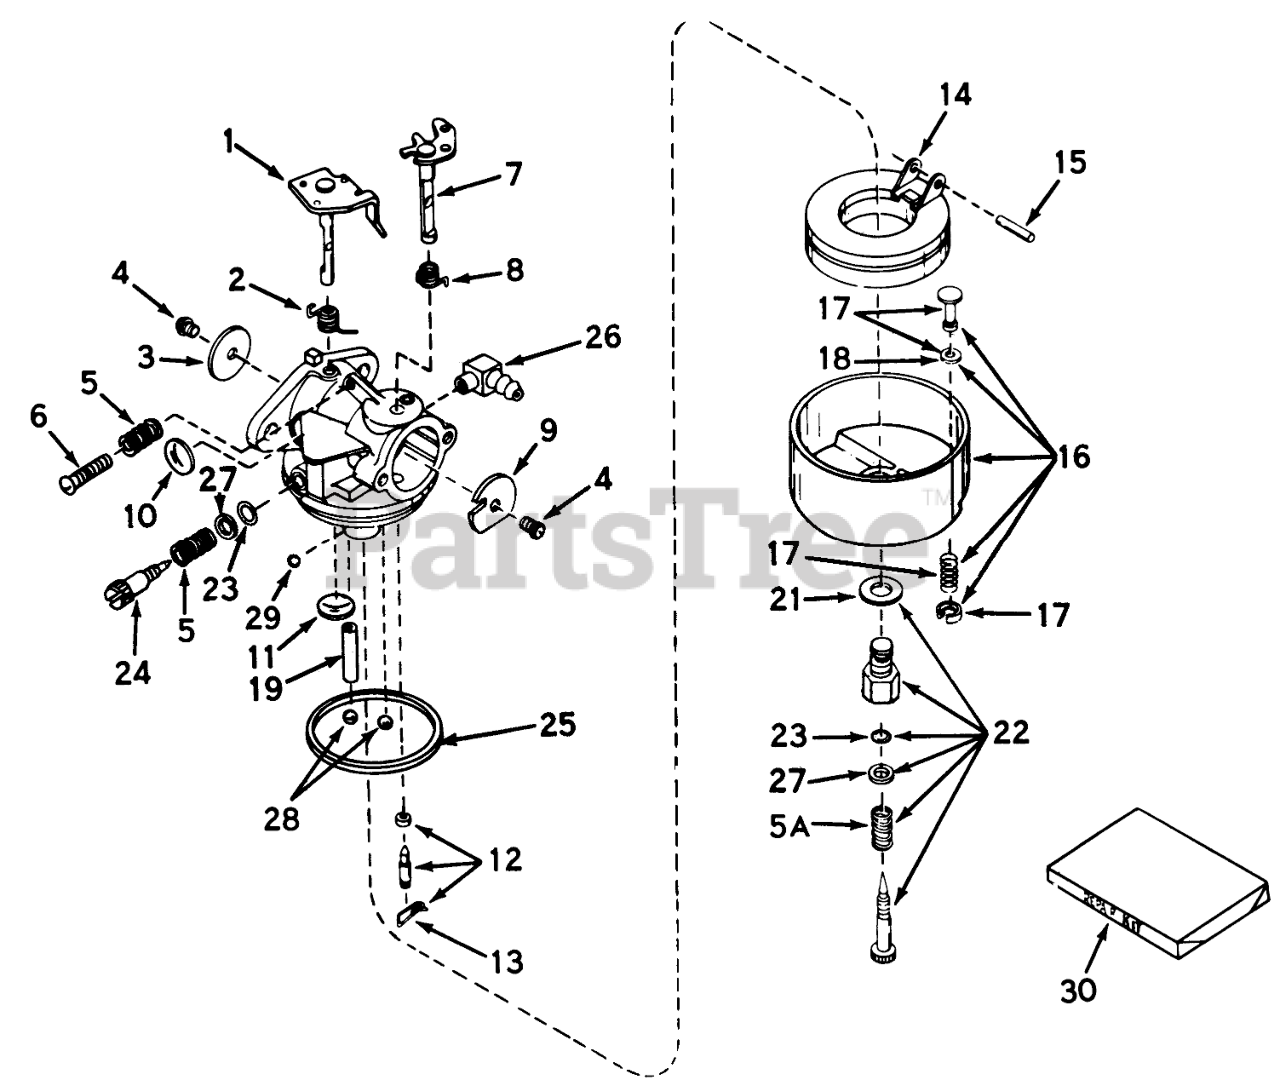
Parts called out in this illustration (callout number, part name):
1	Throttle Shaft and Lever ASM
2	Spring, Throtte Return
3	Shutter-Throttle
4	Screw-Shutter
5	Spring-Tension
6	Screw-Throttle Crack Screw / Idle Speed
7	Shaft& Lever Assy., Choke
8	Spring, Choke return
9	Shutter, Choke
10	Plug-Welch, Idle Mixture Well
11	Plug-Welch, Atmospheric Vent
12	Inlet Needle, Seat & Clip Assy. (Incl. No 13)
13	Clip-Spring
14	Float,Carburetor
15	Shaft-Float
16	Bowl & Drain Assy., Float (Incl. No. 17)
17	Plunger Assy., Drain (Incl. No. 18)
18	Gasket-Plunger, Drain
21	Washer-Bowl Nut
22	Adjustment Screw Assy., Main (Incl. Nos. 5A, 21, 23 & 27)
23	"O"Ring
24	Screw, Idle Adj.
25	O Ring-Bowl, Float
26	Fitting Fuel Inlet
28	Plug, Cup
29	BalI, Steel
30	Repair Kit
